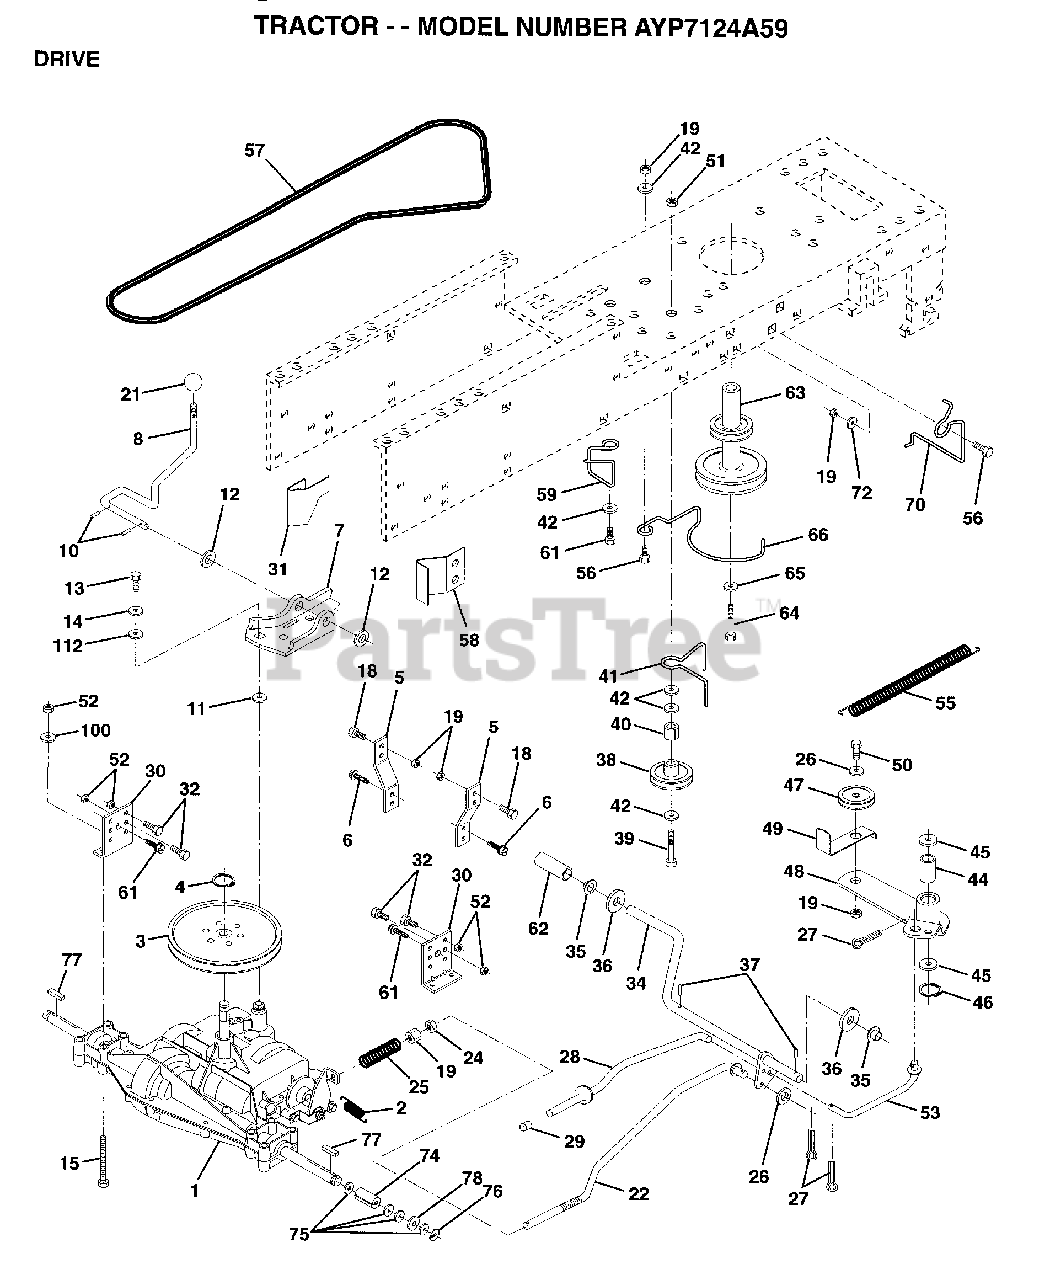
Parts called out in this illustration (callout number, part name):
3	PULLEY TRANS
5	STRAP TORQUE
6	SCREW
8	SHIFT ROD
10	PIN COTTER 1/8
11	WASH-SHFT PLT LT
12	WASHER
13	BOLT.1/4-28.W/PAT
14	LOCKWASHER
15	BOLT HEX
18	BOLT
19	NUT
21	KNOB T (1/2-HOLE)
22	BRAKE ROD
24	NUT
25	SPRING ROD LT
26	WASHER
27	COTTER PIN
28	ROD PARK BRAKE
29	PLUNGER CAP T
30	TRANSAXLE MTG BKT
31	"KEEPER,BELT LH T"
32	BOLT
35	NYLON BEARING
36	WASHER LT
38	PULLEY.IDLER.FLAT
39	BOLT
40	SPACER T
41	BELT KEEPER LT
42	WASHER
44	"LY, BEARING"
45	WASHER LT
46	KLIP RING
48	ARM IDLER
49	RETAIN BELT
53	"LINK, CLUTCH T"
55	"SPRING, RETURN LT"
58	"KEEPER,BELT RH T"
59	KEEPER BELT CNTSP
61	SCREW
62	PEDAL COVER T
63	PULLEY.ENGINE
64	BOLT
65	LOCKWASHER
66	KEEPER.BELT.ENG.L
70	KEEPER BELT ENG
72	WASHER
74	SPACER LT
75	WASHER
76	E-RING LT
77	SQUARE KEY
78	WASHER
100	WASHER M
112	WASHER LT
